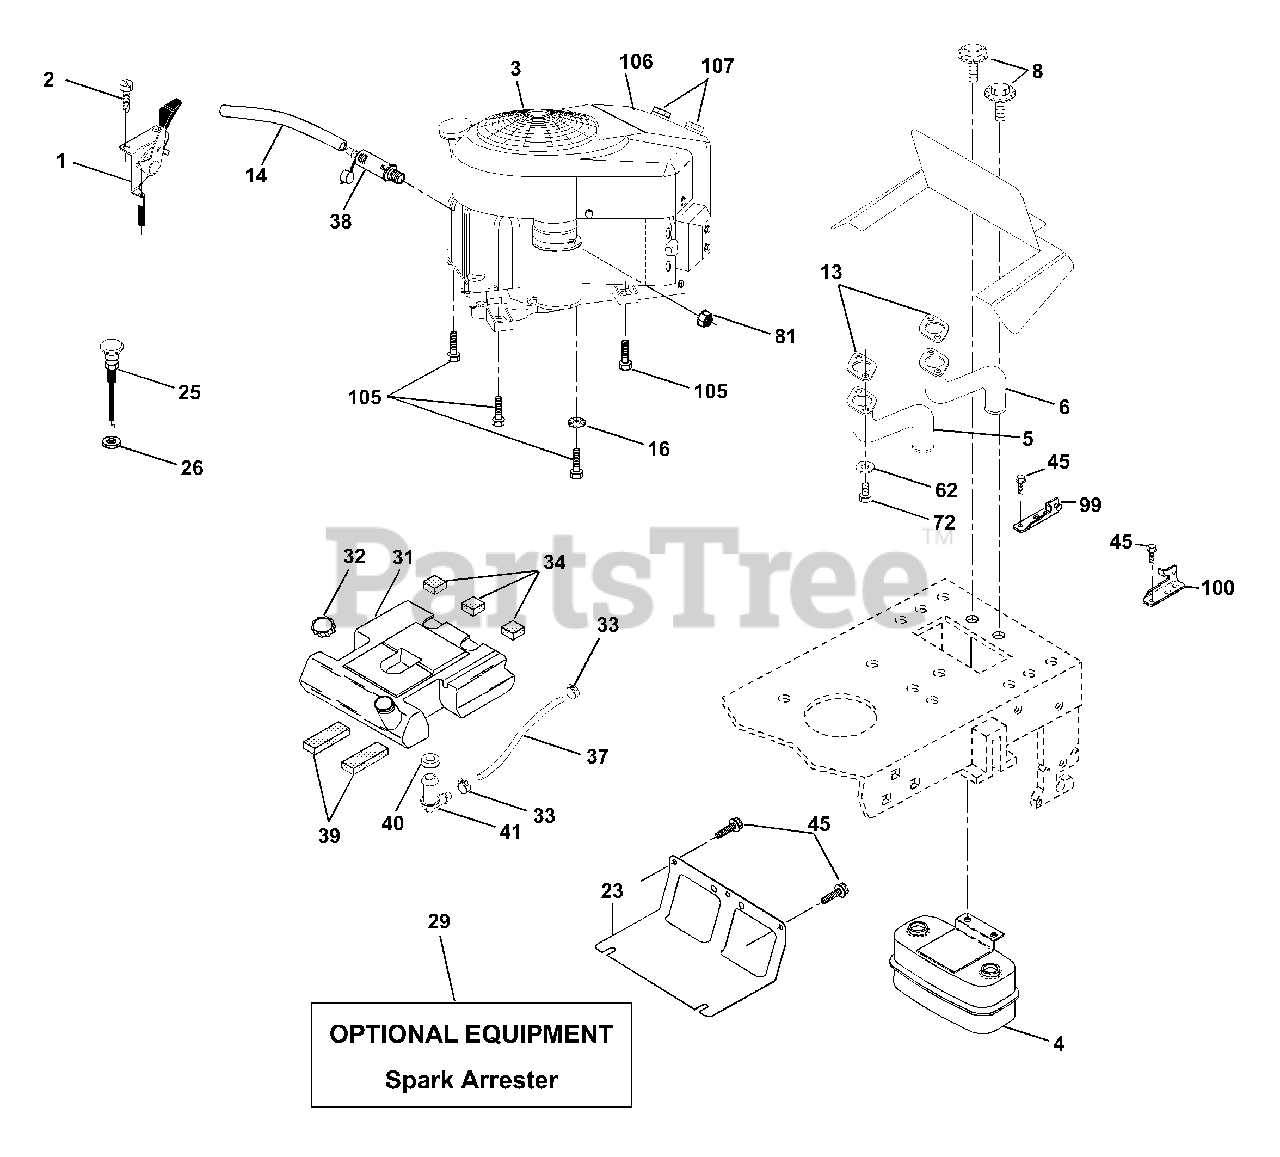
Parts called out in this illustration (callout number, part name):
1	Control, Throttle
2	Screw, Hex Head, Thread Cutting 1/4-20 x 5/8
4	Muffler
5	Tube, Exhaust, LH
6	Tube, Exhaust, RH
7	Clip Insulated
8	Bolt 5/16-18 UNC x 3/4 w/Sems
10	Shield, Browning
13	Muffler Gasket
14	Tube Drain Oil Easy
16	Washer, Lock, External Tooth 3/8
23	Shield, Browning / Debris Guard
25	Choke Control
26	Nut, Keps 3/8-24 UNF
29	Kit, Spark Arrestor
31	Tank Fuel 3 50 Rear
32	Cap Fuel Gauge
33	Clamp, Hose
34	Pad, Spacer
37	Line, Fuel
38	Plug Drain Oil Easy
39	Pad, Idler
40	Bushing
41	Stem, Fuel Tank
45	Screw Hex wsh Thdrol 3/8-16 x 3/4
62	Washer Lock 5/16
72	Screw Hex Hd Cap 5/16-18 x 3/4
81	Nut Keps Hex 1/4-20 Unc
99	Bracket Asm Pivot Lh Raised
100	Bracket Asm Pivot Rh Raised
105	Screw 3/8-16 x 1
106	Control Cover
